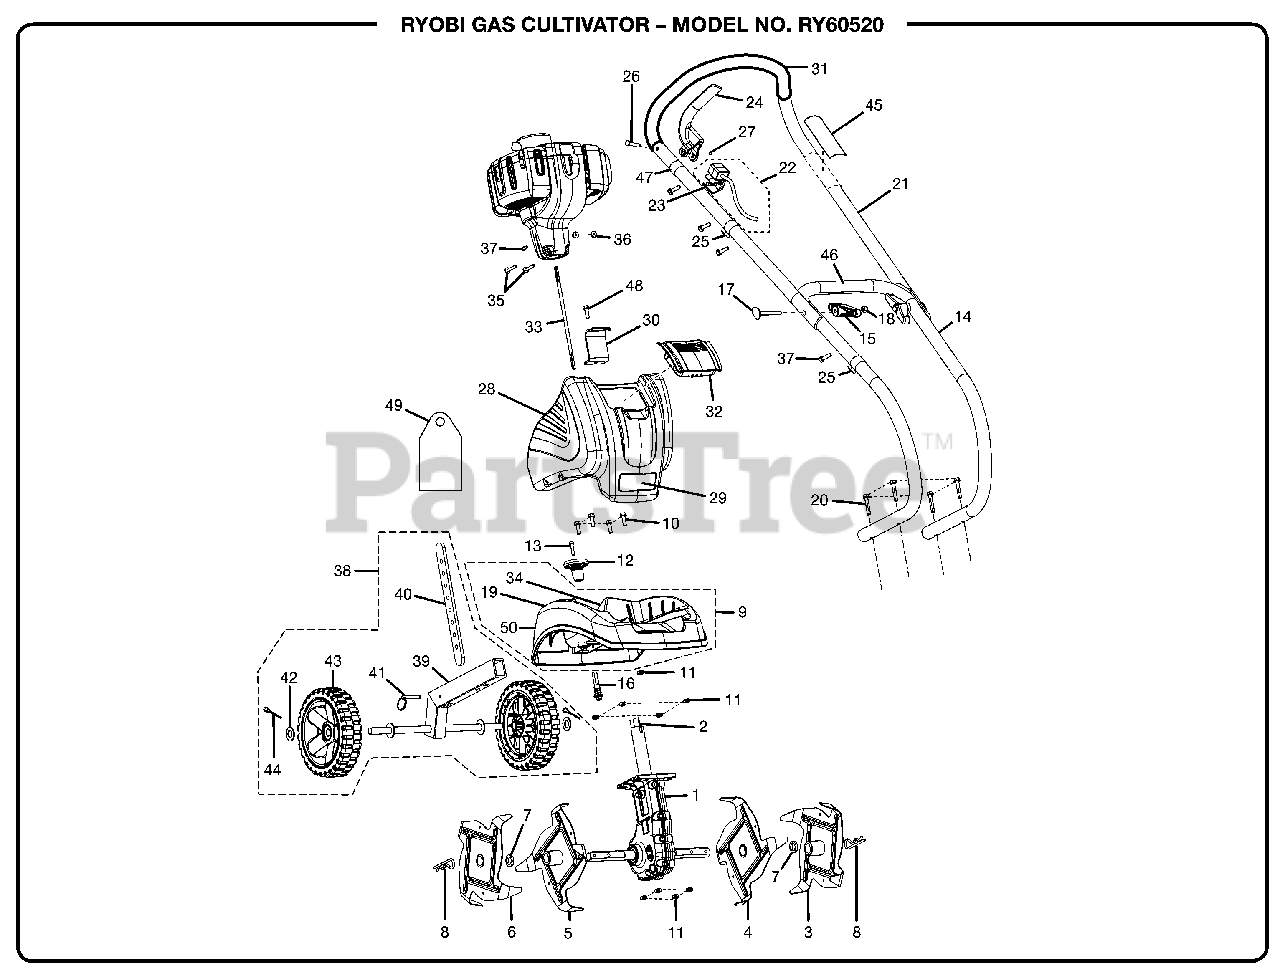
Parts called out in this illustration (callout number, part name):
1	GEAR BOX ASSEMBLY WITH TUBE
2	LINER - DRIVE TUBE
3	TINE A, OUTER RIGHT
4	TINE B, INNER RIGHT
5	TINE C, INNER LEFT
6	TINE D, OUTER LEFT
7	FELT WASHER
8	CLEVIS CLIP
9	TINE SHIELD ASSEMBLY
10	BOLT (1/4-20 X 1 in.)
11	LOCK NUT (1/4-20)
12	RECEIVER RETAINER KNOB
13	SCREW (M5 X 16 mm PAN HD.)
14	LOWER HANDLE ASSEMBLY
15	KNOB (1/4-20)
16	RECEIVER RETAINER ASSEMBLY
17	CARRIAGE BOLT (1/4-20 X 2-1/4 in.)
18	ACORN NUT (1/4-20 in.)
19	WARNING LABEL, FOOT
20	HANDLE BOLT (1/4-20 X 1.53 in.)
21	UPPER HANDLE ASSEMBLY
22	THROTTLE CABLE ASSEMBLY
25	CABLE RETAINER
26	CLEVIS PIN
27	RETAINING RING
28	TANK - BALLAST ASSEMBLY
29	LOGO LABEL
30	MOUNTING BRACKET
32	BALLAST TANK LID
33	FLEXIBLE DRIVE SHAFT
34	WHEEL ACCESSORY LABEL
35	BOLT (10-24 X 1-1/4 in.)
36	NUT (10-24)
37	SCREW (8-16 X 1/2 in.)
38	WHEEL/DRAG STAKE ASSEMBLY
39	FRAME ASSEMBLY
40	DRAG STAKE
41	QUICK RELEASE PIN
42	FLAT WASHER
43	WHEEL ASSEMBLY (6 in DIA.)
44	COTTER PIN
45	BOOM WARNING LABEL
46	STARTING LABEL
47	PLASTIC ROPE CLIP
48	BOLT (1/4-20 x 5/8 in.)
49	WARNING HANG TAG
50	TINE SHIELD WARNING LABEL
